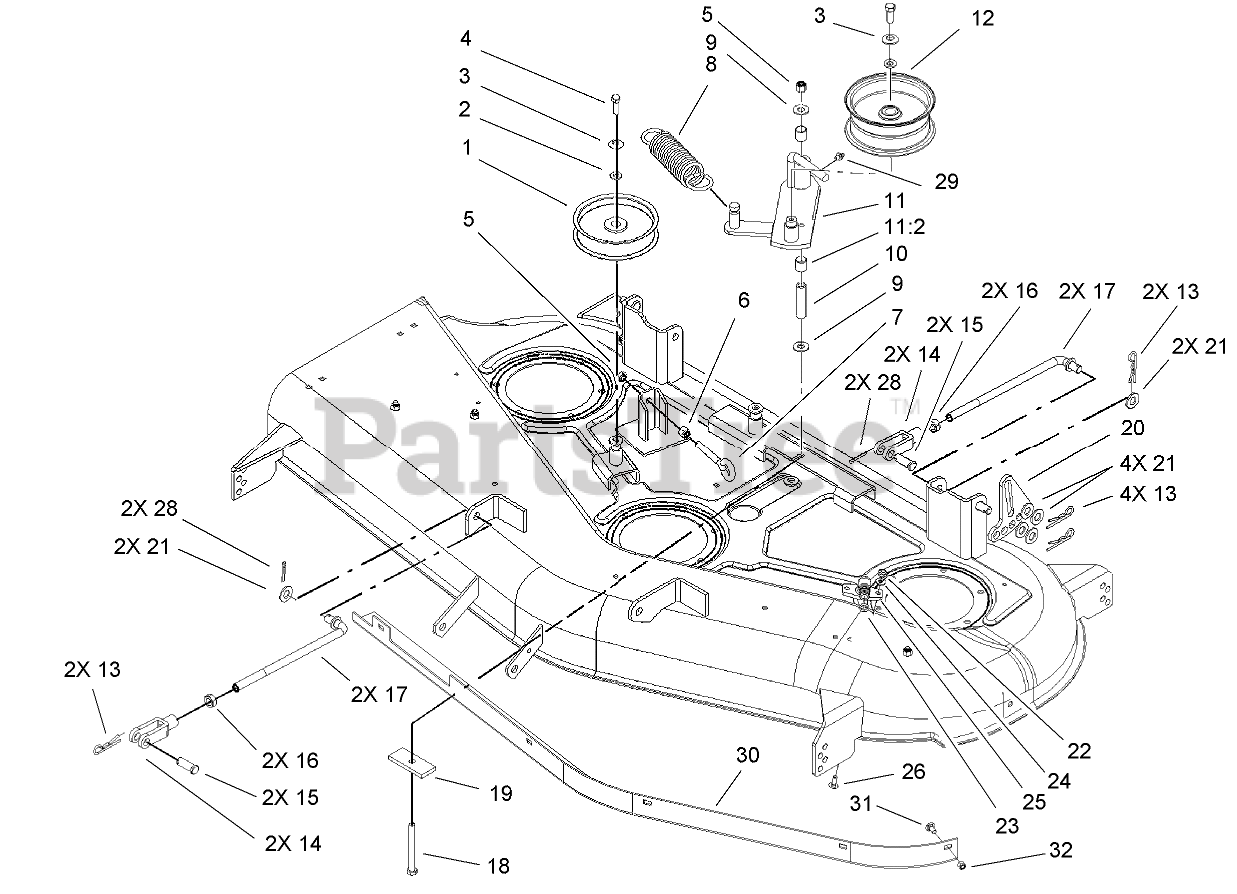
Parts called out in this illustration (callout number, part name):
1	PULLEY-IDLER
2	WASHER-FLAT
3	WASHER-BELLEVILLE
4	SCREW-HH
5	NUT-LOCK, NI
6	NUT-HEX
7	BOLT-EYE
8	SPRING-EXTENSION
9	WASHER-HARDENED
10	BUSHING-PIVOT, IDLER
11	IDLER ARM ASM
11:2	SLEEVE-BEARING
12	PULLEY-IDLER, FLAT
13	PIN-COTTER
14	CLEVIS
15	PIN-CLEVIS
16	NUT-JAM
17	ROD-TRUNION
18	SCREW-HH
19	PLATE-BOLT, RETAINER
20	LINK-HOC, ADJUSTING
21	WASHER-FLAT
22	NUT-LOCK, NI
23	O-RING
24	WASHER-FLAT
25	FITTING-WASHOUT
26	BOLT-CARR
28	PIN-COTTER
29	FITTING-GREASE
30	BAFFLE
31	BOLT-CARR
32	NUT-LOCK, NI
